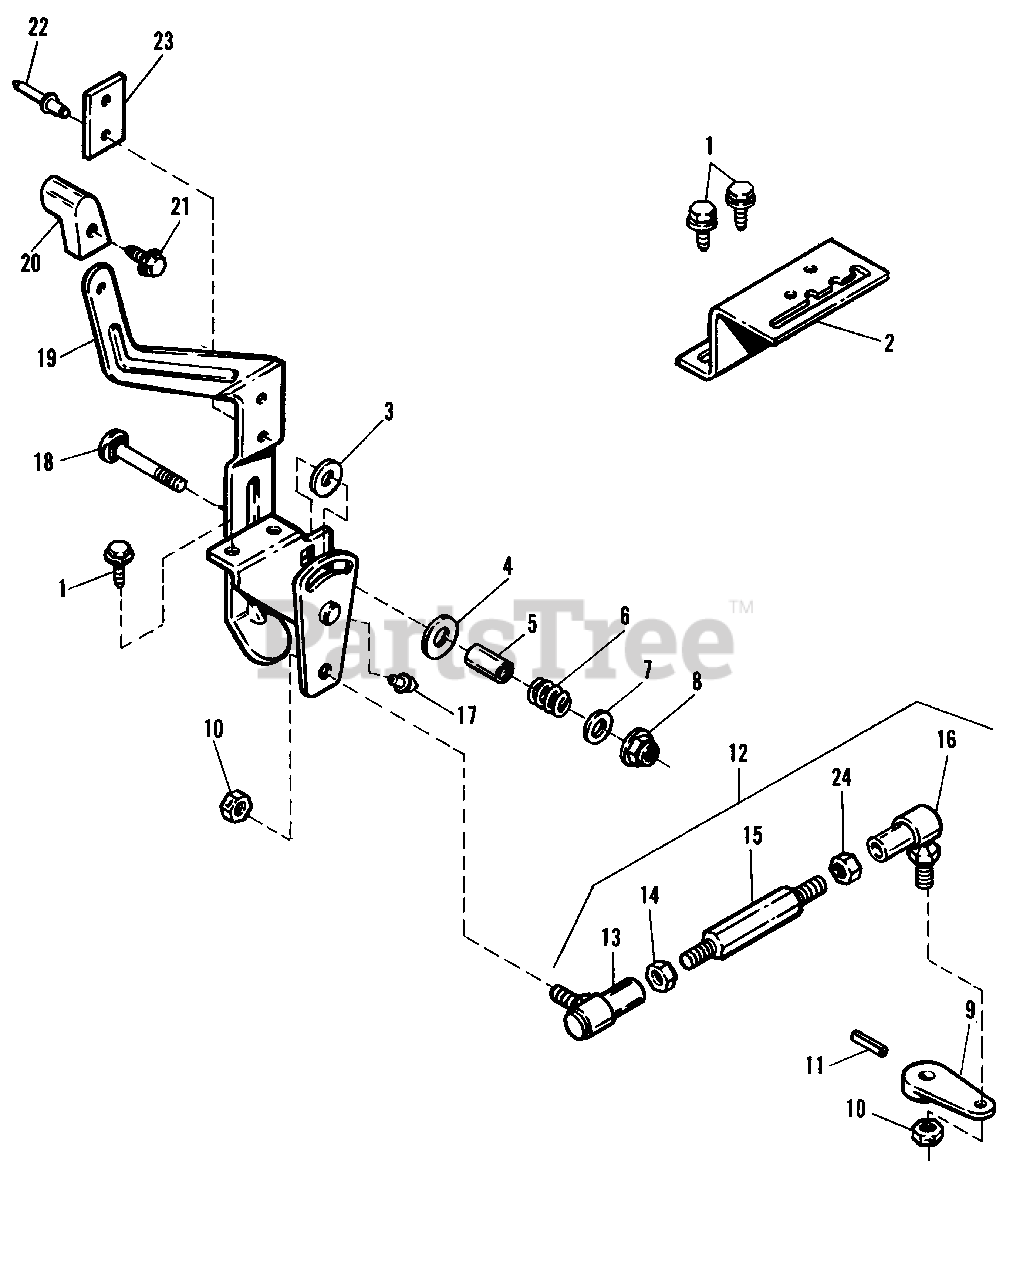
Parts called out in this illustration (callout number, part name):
1	SCREW, Taptite, 5/16-18 x 3/4
3	WASHER, 21/32 x 1-1/4 x 1/16
4	WASHER, 11/32 x 1-1/2 x 7/64
6	SPRING, Compression
7	WASHER, 11/32 x 1
8	NUT, Hex Lock, Exna, 5/16-18
9	ARM-CONTROL, Directional
10	NUT, Centerlock, 3/8-24
11	PIN, Spring, 5 mm x 45 mm
12	SPEED CONTROL BALL JOINT ASSY. (Incl. Ref. Nos. 13-16, 24)
13	BALL JOINT, L.H.
14	NUT, Jam, 3/8-24, R.H.
15	ADJUSTOR, Speed-Link
16	BALL JOINT, R.H.
17	GREASE FITTING
18	CARRIAGE BOLT, 5/16-18 x 2-1/2
19	SUPPORT ASSY., Control (Incl. Ref. Nos. 17, 22 & 23)
21	SCREW, Plastite, 1/4-20 x 1
22	RIVET, Tubular
23	PLATE, Wear
24	NUT, Jam, 3/8-24, L.H.
